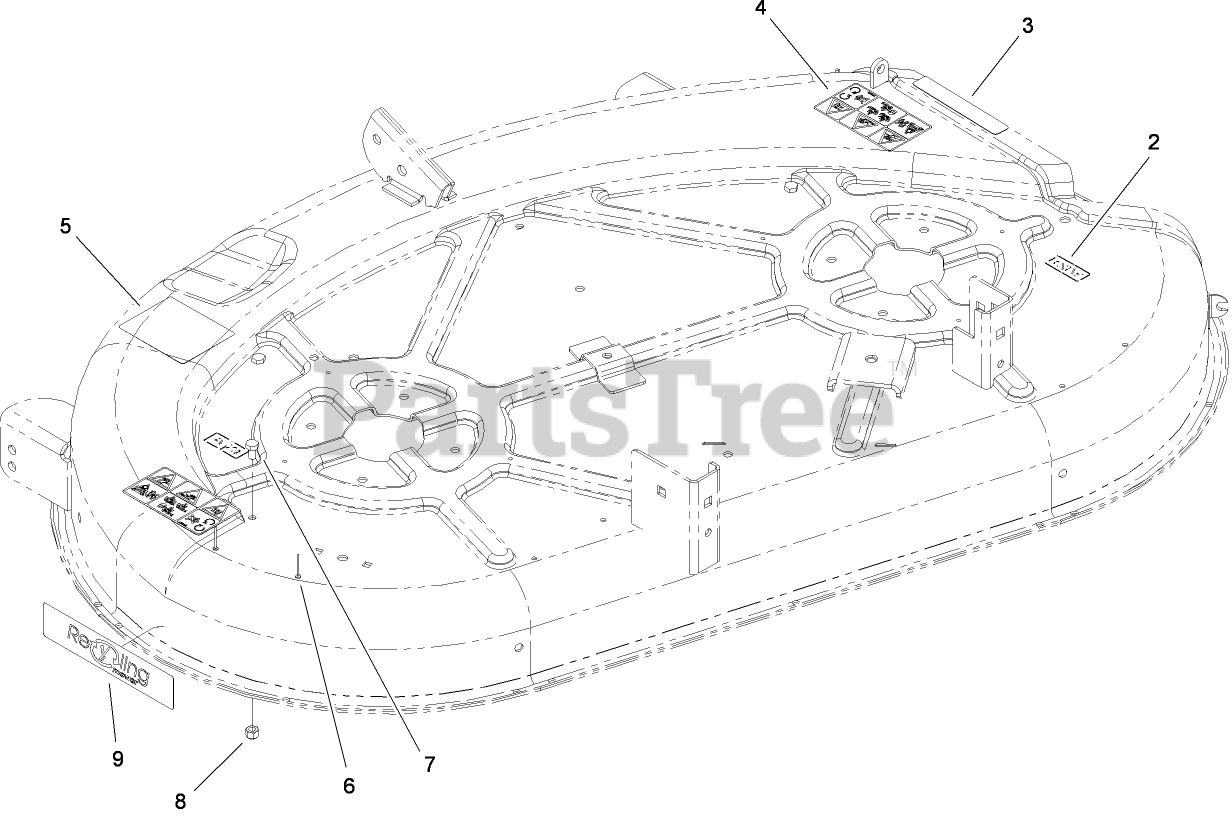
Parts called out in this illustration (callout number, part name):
2	DECAL-DANGER
3	DECAL-DANGER
4	DECAL-DANGER
5	DECAL-ROUTING, BELT
6	RIVET-BLIND
7	SCREW-HH
8	NUT-LOCK, NI
9	DECAL-RECYCLING
